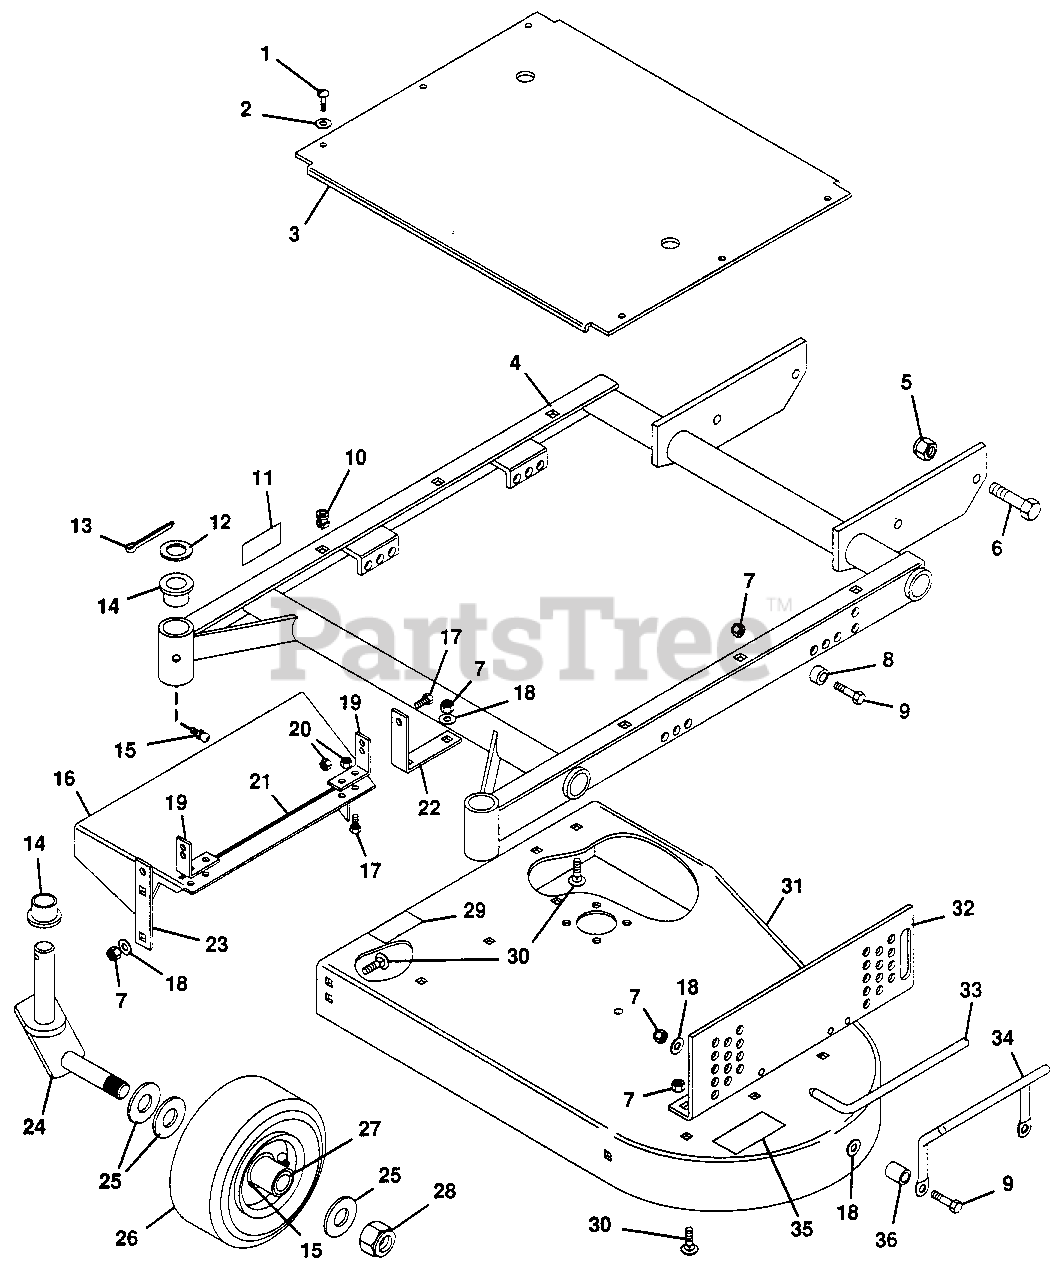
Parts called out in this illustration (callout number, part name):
1	SCREW, 1/4-20X.50 SELF TAPPING
2	WASHER, FLAT .281X.625X.065
3	COVER, BELT
4	WELDMENT, MOWER FRAME
5	NUT, LOCK 5/8-11
6	BOLT, HEX 5/8-11X1.50
7	NUT, LOCK 3/8-16
8	BUSHING, ST. .391X.621X.676 STL.
9	BOLT, HEX 3/8-16X1.50
10	GROMMET, PLASTIC
11	DECAL, DANGER HAND
12	RACE, BEARING THRUST
13	PIN, COTTER .187X1.50
14	BUSHING, FLANGE NYLON
15	FITTING, LUBE 1/4-28
16	CHUTE, DISCHARGE
17	BOLT, HEX 5/16-18X.75
18	WASHER, FLAT .406X.812X.065
19	BRACKET
20	NUT, LOCK 5/16-18
21	DECAL, WIDTH OF CUT
22	BRACKET
23	BRACKET
24	WELDMENT, CASTER FORK
25	WASHER, FLAT .812X1.496X.134
26	WHEEL, GAUGE
27	BEARING, GAUGE WHEEL
28	NUT, LOCK 3/4-10
29	DECAL, WARNING EYE
30	BOLT, 3/8-16X1.00 RD HD SQ NK
31	WELDMENT, 32" PRO DECK
32	BRACKET, MOWER SIDE SUPPORT R.H.
32	BRACKET, MOWER SIDE SUPPORT L.H.
33	PIN, MOWER LOCKING
34	HANDLE
35	DECAL, DANGER FOOT
36	BUSHING
NS	DECAL, GRAVELY LOGO
NS	DECAL, PRO-32
